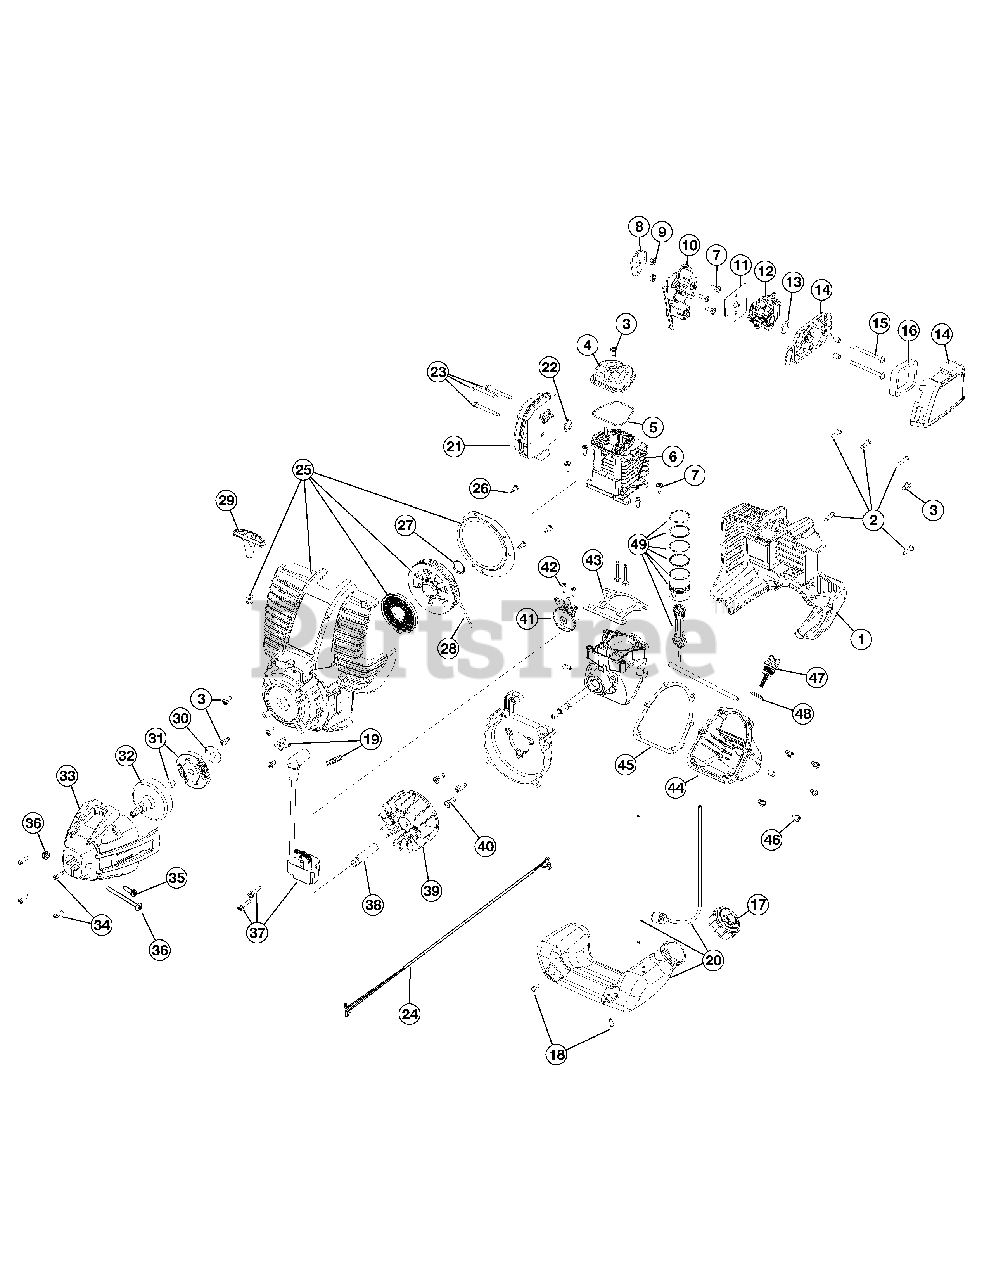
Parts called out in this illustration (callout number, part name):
1	Engine Cover
4	Valve Cover
5	Valve Cover Gasket
6	Cylinder Assembly (Incl. Ref No. 5, 7 & 43)
7	Cylinder Screw
8	Insulator Gasket
9	Nut
10	Insulator (Incl. Ref No. 11)
11	Carburetor Gasket
12	Carburetor w/Primer
13	Carburetor O-Ring
14	Air Filter Cover Assembly (Incl. Ref No. 16)
15	Air Filter Mounting Screw
16	Air Filter
17	Fuel Cap
19	Clip Nut
20	Fuel Tank Assembly (Incl. Ref No. 17)
21	Muffler Assembly (Incl. Ref No. 22 & 23)
22	Muffler Gasket
23	Muffler Mounting Screw
24	Lead Wire
25	Starter Housing Assembly (Incl. Ref No. 3 & 26-29)
26	Plate Screw
27	Push Nut
29	Pull Handle
30	Washer
31	Clutch Assembly
32	Clutch Drum
33	Clutch Cover Assembly (Incl. Ref No. 34-36)
34	Cover Screw
35	Anti-Rotation Screw
36	Clamping Screw Assembly
37	Ignition Module Assembly
38	Spacer
39	Flywheel
40	Shroud Screw
41	Cam Bracket Assembly (Incl. Ref No. 42)
42	Cam Bracket Screw
43	Cylinder Gasket
44	Oil Pan (Incl. Ref No. 45 & 46)
45	Oil Pan Gasket
46	Oil Pan Screw
47	Dipstick Assembly (Incl. Ref No. 48)
49	Piston Assembly
